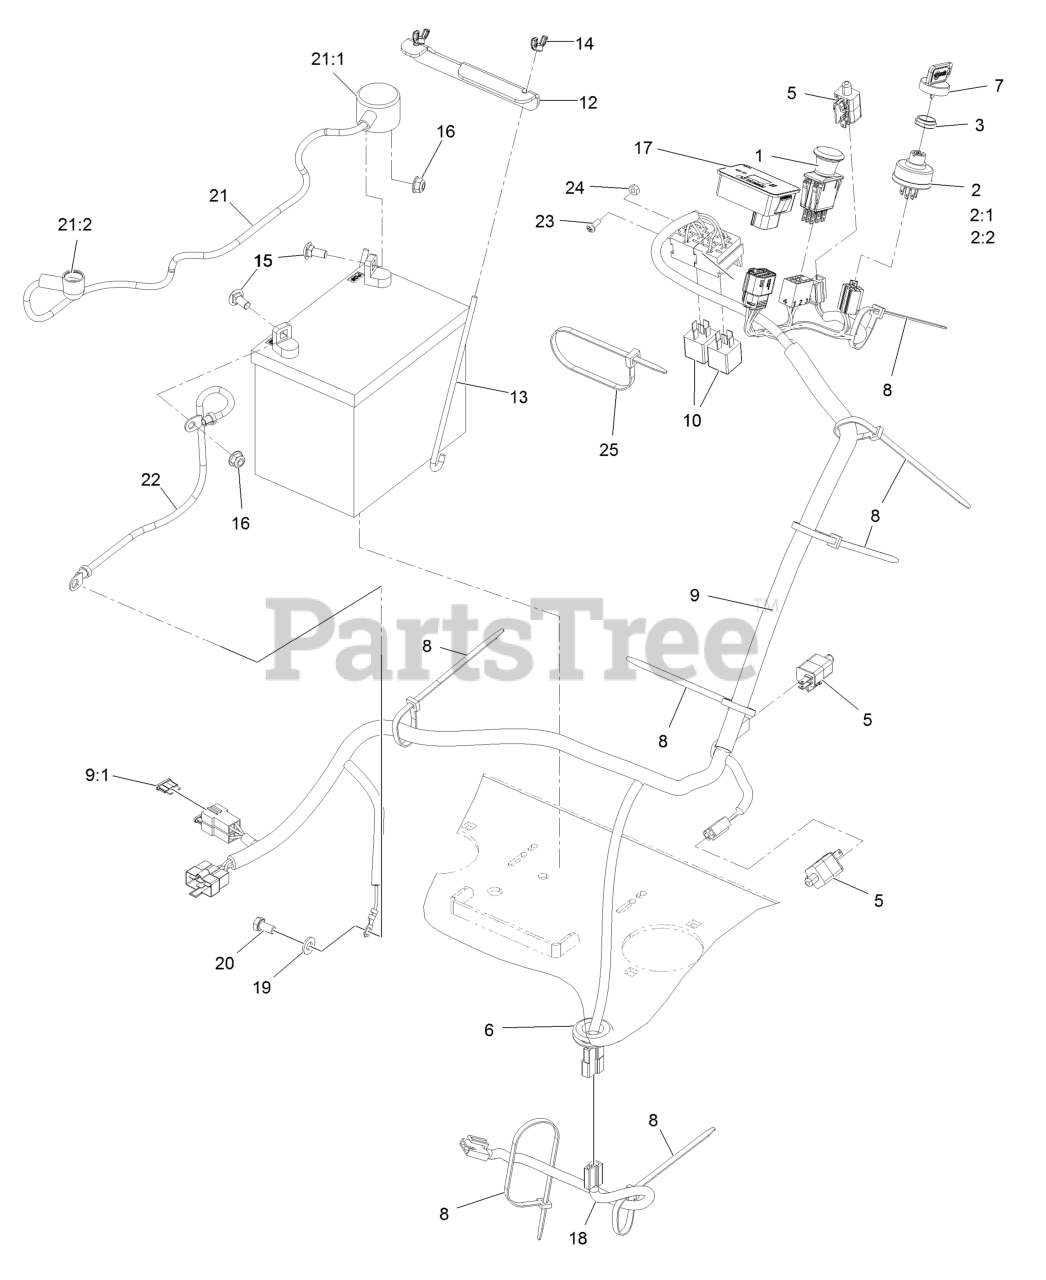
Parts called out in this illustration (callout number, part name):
1	SWITCH-PTO
2:1	WASHER-LOCK
3	NUT-SWITCH, IGNITION
6	GROMMET
7	KEY-IGNITION
8	TIE-PLASTIC
9	HARNESS-MAIN TTX KAWASAKI
9:1	FUSE-BLADE TYPE, 20 AMP
13	BOLT-HOLDDOWN
14	WINGNUT
15	BOLT-CARR
16	NUT-HF, NI
17	MODULE-HOUR METER
18	HARNESS-CLUTCH PIGTAIL
19	WASHER-PLAIN
20	SCREW-HH
21	POSITIVE BATTERY CABLE AS
21:1	INSULATOR-SOLENOID
21:2	INSULATOR-BATTERY
24	NUT-LOCK, NI
25	TIE-PLASTIC
